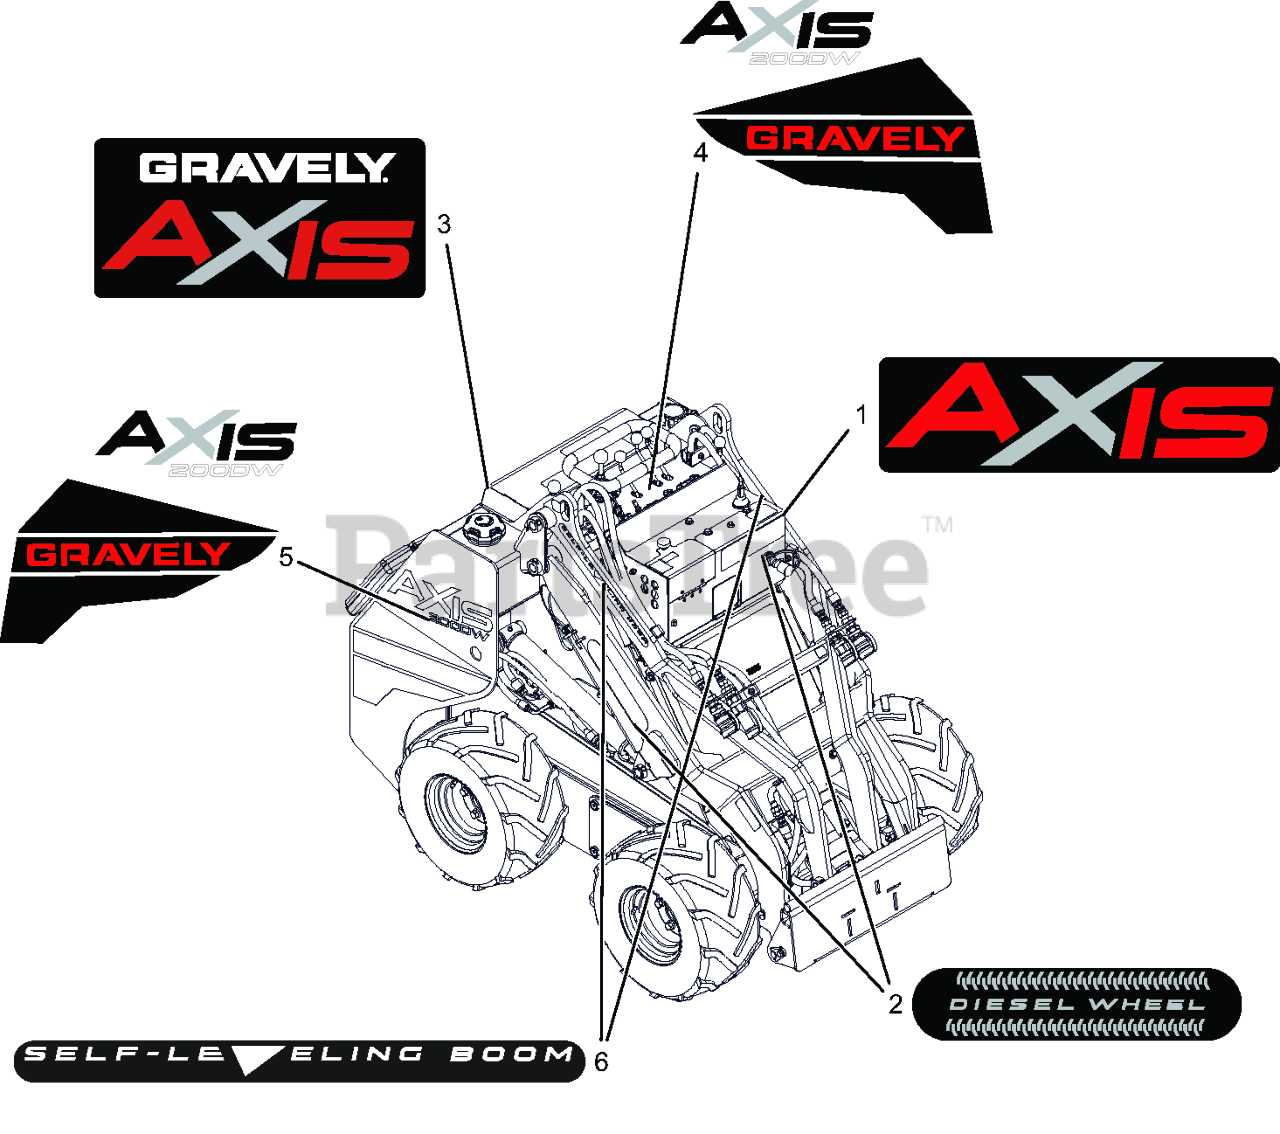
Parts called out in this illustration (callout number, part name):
1	DECAL, AXIS FRONT
2	DECAL, DIESEL WHEEL
3	DECAL, AXIS REAR
4	DECAL, 200 DW LEFT
5	DECAL, 200 DW RIGHT
6	DECAL, SELF LEVELING
